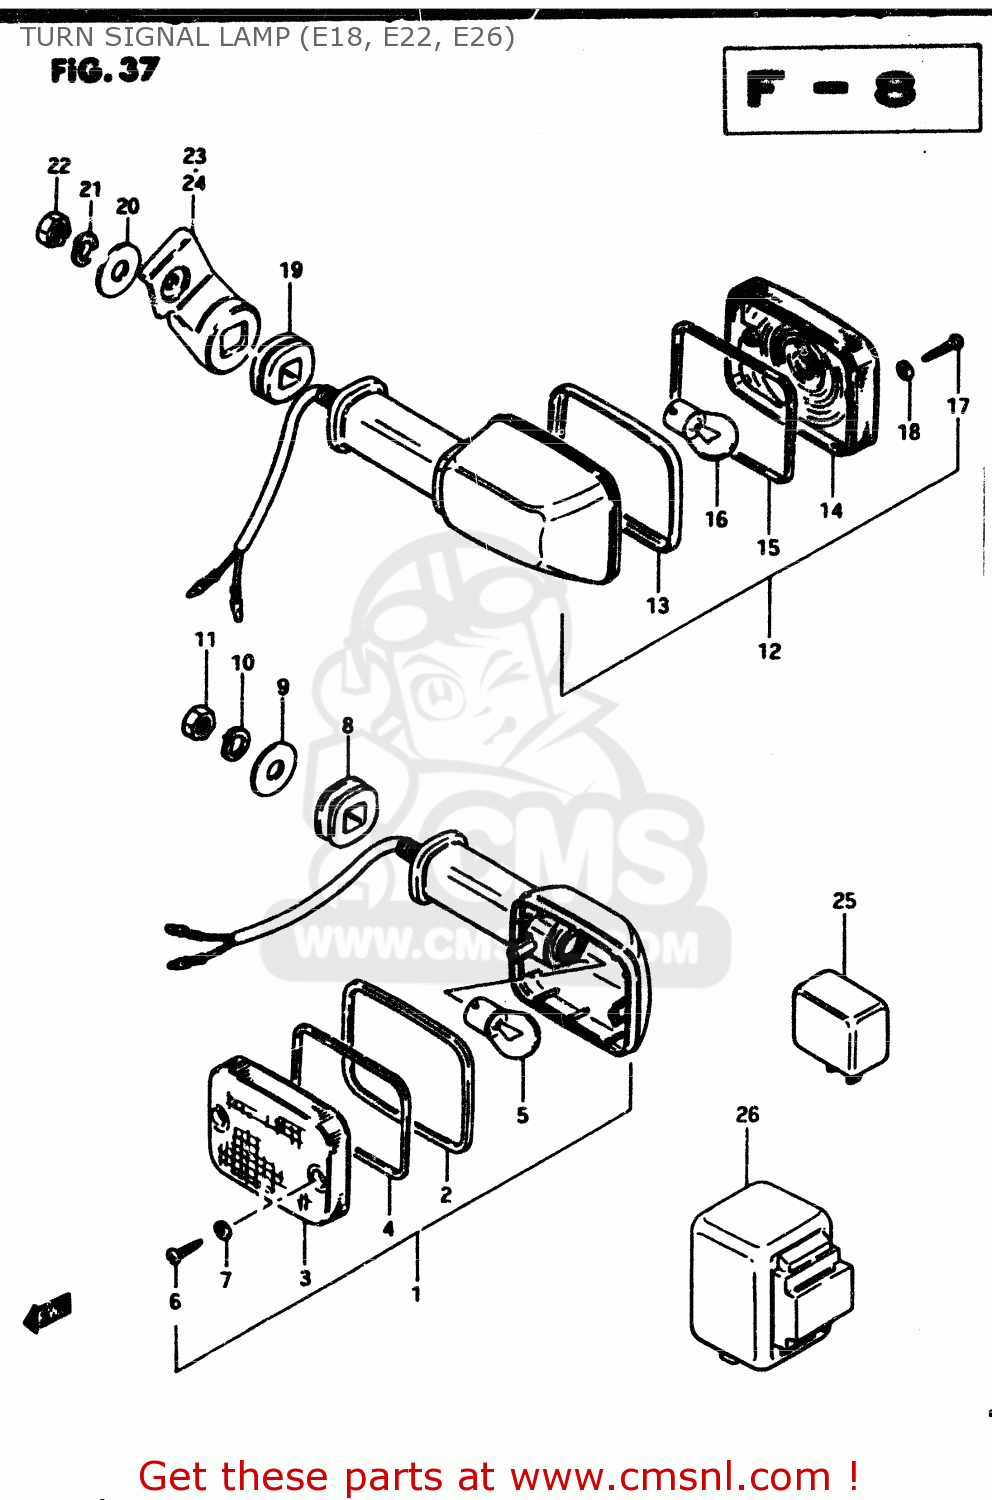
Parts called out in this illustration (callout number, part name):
1	LAMP ASSY,FR T
2	RIM
3	LENS
4	GASKET (NAS)
5	BULB(12V21W)
6	SCREW
7	GASKET (NAS)
8	CUSHION
9	WASHER (10.5X30X2.3)
10	LOCK WASHER
11	NUT
12	LAMP ASSY,RR T
13	RIM
14	LENS
15	GASKET (NAS)
16	BULB(12V21W)
17	SCREW
18	GASKET (NAS)
19	CUSHION
20	WASHER (10.5X30X2.3)
21	LOCK WASHER
22	NUT
23	BRACKET,REAR TURN SIGNAL
24	BRACKET,REAR TURN SIGNAL
25	RELAY,TURN SIGNAL
26	RELAY, TURN SIGNAL
